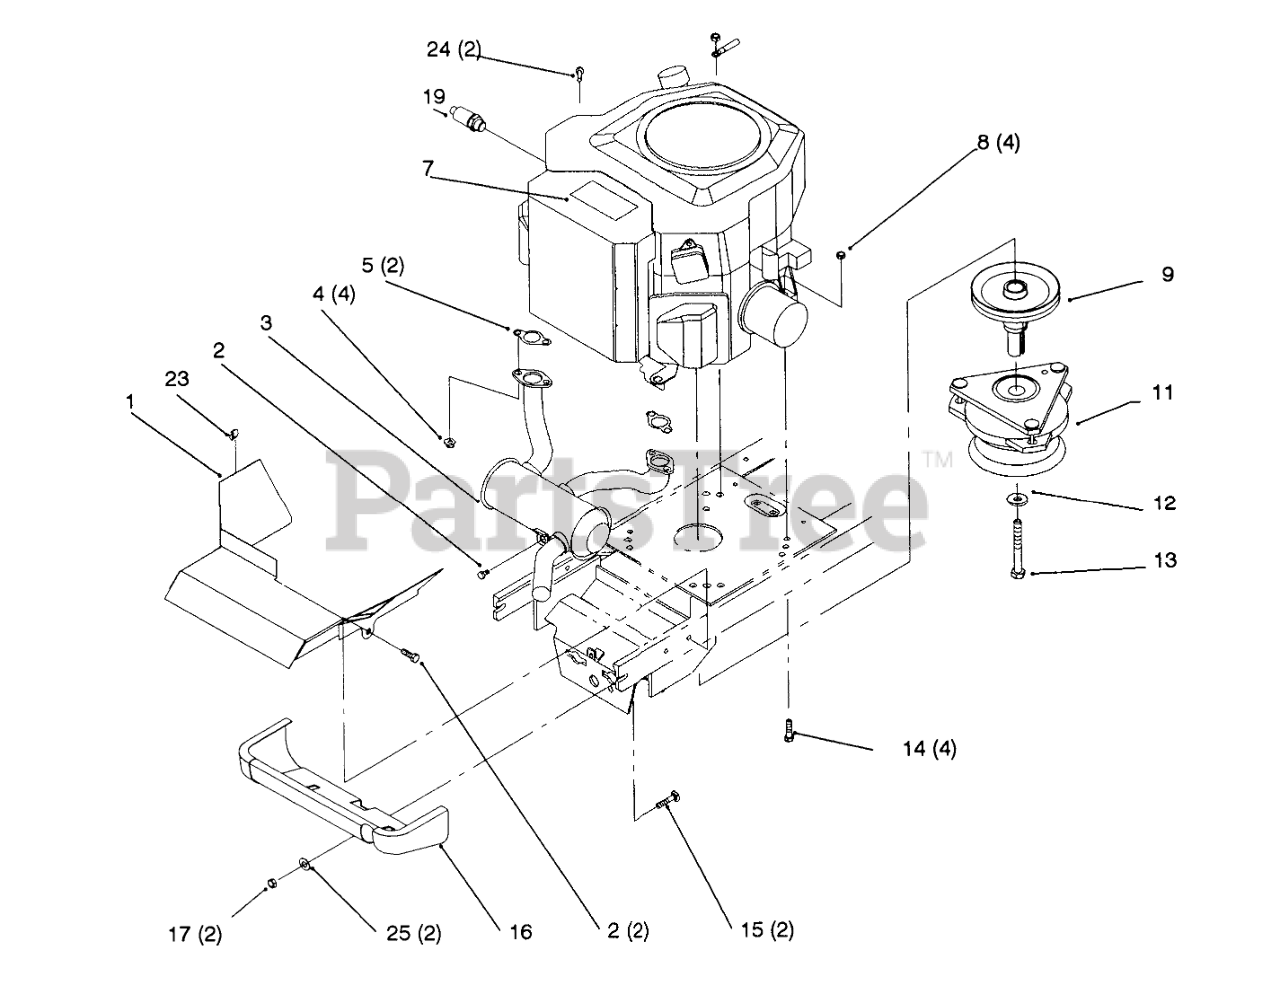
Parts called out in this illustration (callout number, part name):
1	Baffle-MufRer (Only On:72103)
2	Screw-HWHTF (Only On:72103)
3	Muffler (Only On: 72103)
4	Nut-HHF (Only On: 72103)
5	Gasket-Exhaust (Only On: 72103)
7	Decal-Toro Power Plus 18 (Only On: 72103)
8	Nut-Lock (Only On: 72103)
9	Pulley (Only On: 72103)
11	Clutch-PTO (Only On: 72103)
12	Washer-PTO (Only On: 72103)
13	Screw HH (Only On: 72103)
14	Screw- HH (Only On: 72103)
15	Bolt-CARR (Only On: 72103)
16	Shield-Muffler (Only On: 72103)
17	Nut-Lock (Only On: 72103)
19	Valve-Oil Drain (Only On: 72103)
23	Clip-Wire Retainer (Only On: 72103)
24	Screw-PPH (Only On: 72103)
25	Washer-Flat (Only On: 72103)
